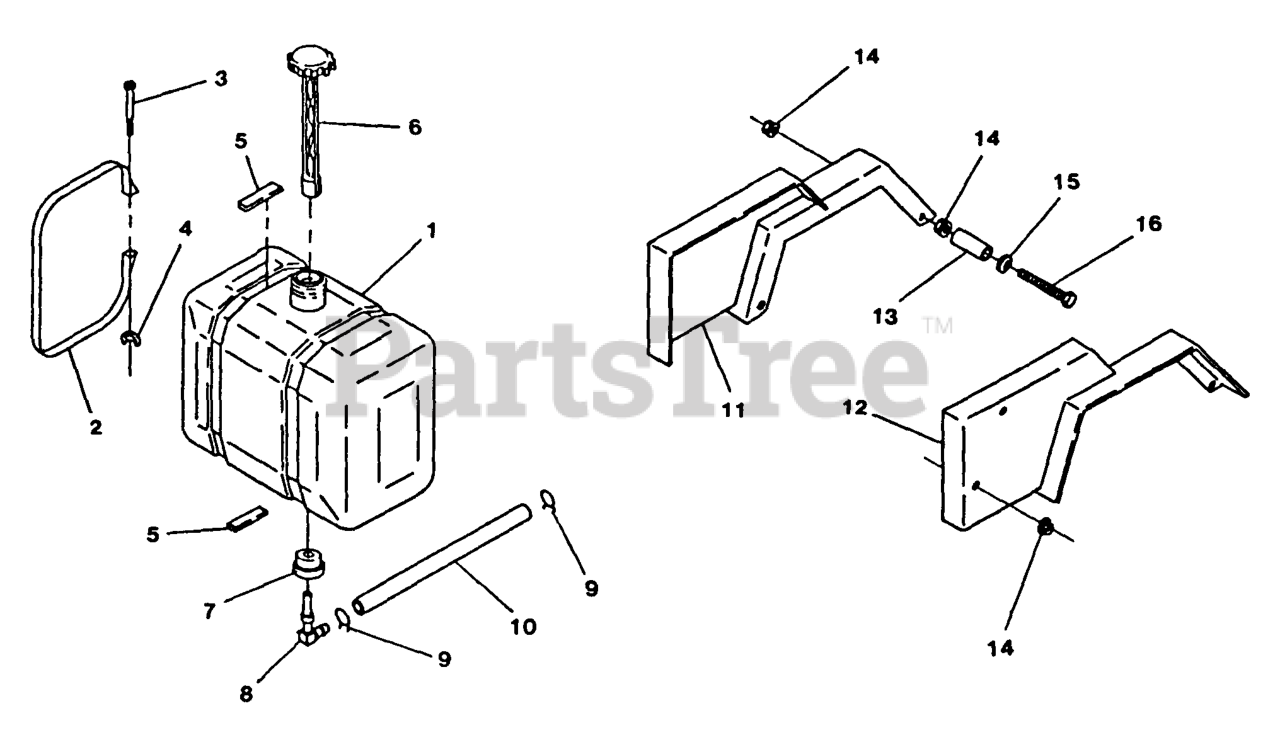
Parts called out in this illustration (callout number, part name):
4	WINGNUT
5	PAD,PLASTIC TANK
13	SPACER-FENDER
